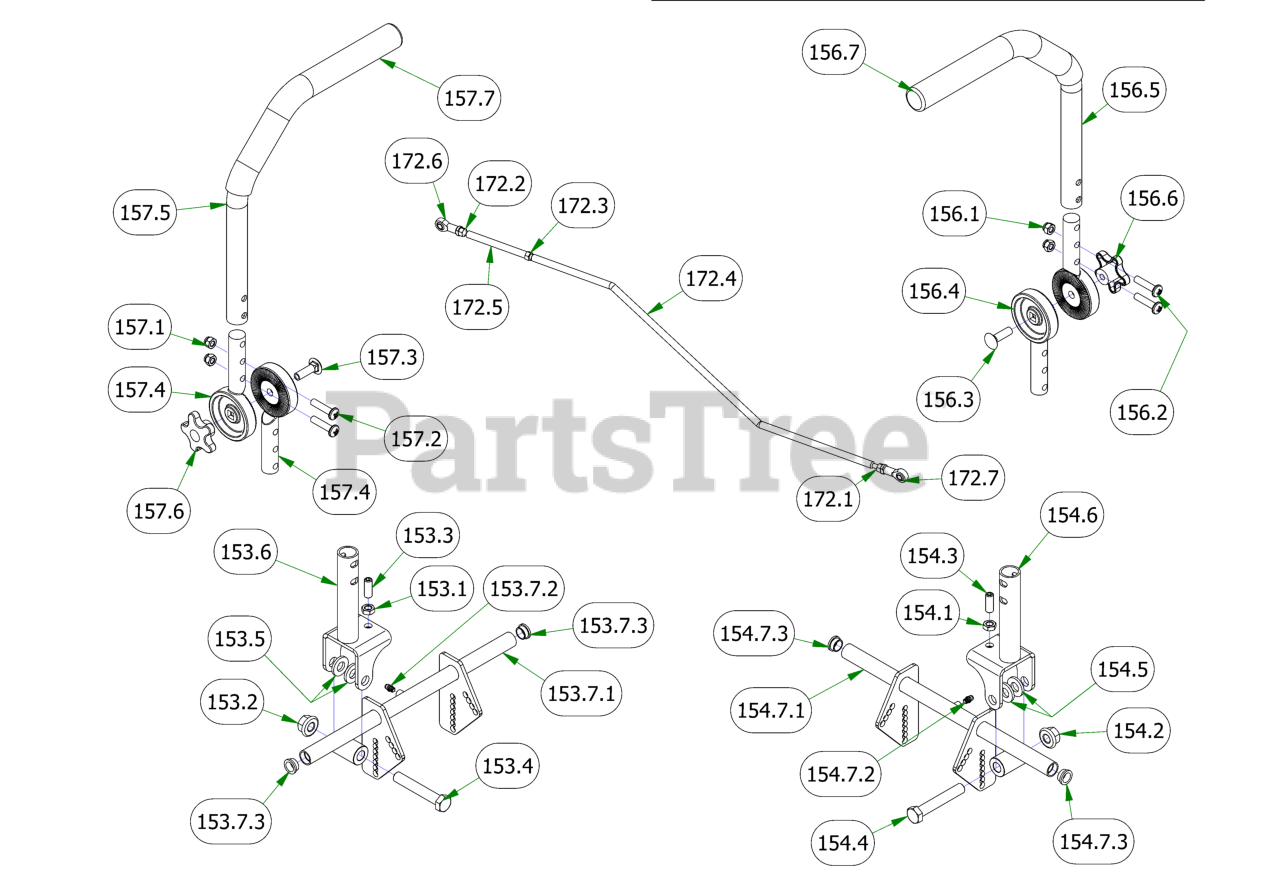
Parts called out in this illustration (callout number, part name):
153	2019 R Series RH Arm Rod Assembly
153.1	3/8-16 Half Jam Nut
153.2	1/2-13 NYLON INSERT FLANGE LOCKNUT ZINC
153.3	3/8-16 X 1 SOCKET SET SCREW (CUP POINT) PLAIN
153.4	1/2-13 X 3 HEX CAP SCREW (GR.5) ZINC
153.5	.505 ID X 1.000 OD X .125 THICK FLAT WASHER NYLON
153.6	Drive Arm Pivot
153.7	2019 Drive Arm Actuator right
153.7.1	2019 Drive Arm Actuator right - Weldment
153.7.2	1/4" Press in Grease Fitting
153.7.3	2019 Drive Arm Bushing
154	2019 R Series LH Arm Rod Assembly
154.1	3/8-16 Half Jam Nut
154.2	1/2-13 NYLON INSERT FLANGE LOCKNUT ZINC
154.3	3/8-16 X 1 SOCKET SET SCREW (CUP POINT) PLAIN
154.4	1/2-13 X 3 HEX CAP SCREW (GR.5) ZINC
154.5	.505 ID X 1.000 OD X .125 THICK FLAT WASHER NYLON
154.6	Drive Arm Pivot
154.7	2019 Drive Arm Actuator left
154.7.1	2019 Drive Arm Actuator left - Weldment
154.7.2	1/4" Press in Grease Fitting
154.7.3	2019 Drive Arm Bushing
156	2019 Left Hand ADJ. Steering Arm Kit
156.1	5/16-18 NYL INS L/N ZC
156.2	5/16-18 x 1 3/8" Futton Head Torx Drive Bolt
156.3	3/8-16 X 1-1/4 CARRIAGE BOLT ZINC
156.4	2019 Steering Arm Adjuster Casting
156.5	2019 Steering Arm Tube
156.6	Black Knob for Adjustable Steering Arm
156.7	Black Steering Arm Grip
157	2019 Right Hand ADJ. Steering Arm Kit
157.1	5/16-18 NYL INS L/N ZC
157.2	5/16-18 x 1 3/8" Futton Head Torx Drive Bolt
157.3	3/8-16 X 1-1/4 CARRIAGE BOLT ZINC
157.4	2019 Steering Arm Adjuster Casting
157.5	2019 Steering Arm Tube
157.6	Black Knob for Adjustable Steering Arm
157.7	Black Steering Arm Grip
172	2019 Renegade Push Rod Assembly
172.1	5/16" RH Fine Threaded Jam Nut
172.2	5/16" LH Fine Threaded Jam Nut
172.3	3/8" Fine Threaded Jam Nut
172.4	2019 Renegade Push Rod
172.5	2019 Renegade Push Rod Adjuster
172.6	Spherical Rod End - Outlaw
172.7	Spherical Rod End - Outlaw
